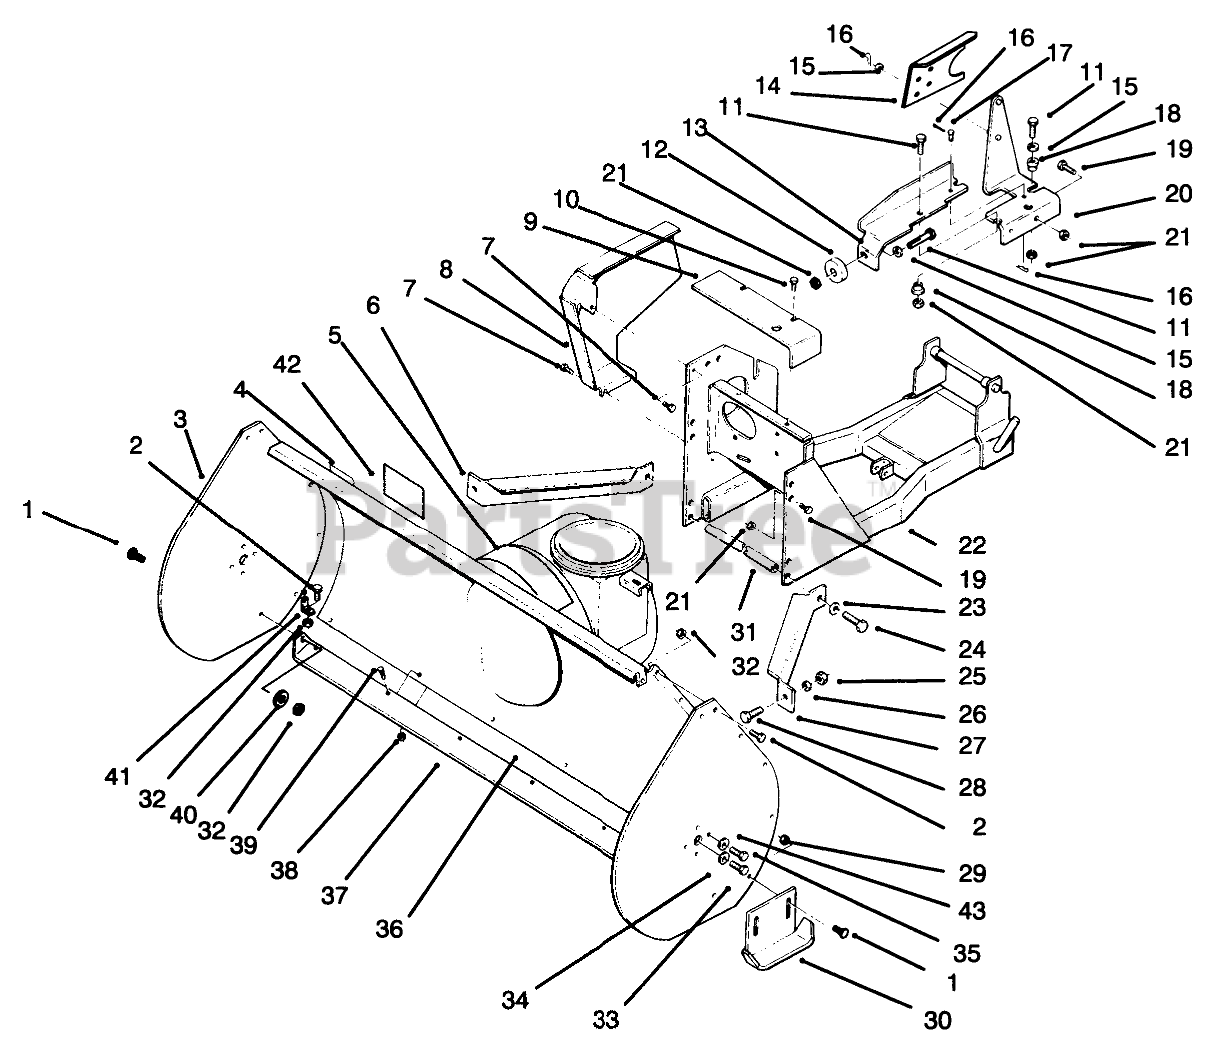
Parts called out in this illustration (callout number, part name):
1	BOLT-CARR
2	SCREW-HH
3	Plate-Side
4	DECAL-DANGER
5	DECAL-ATTACHMENT
6	BRACE-R.H. R
7	SCREW-HWH
8	WLDMT-BELT COVER R
9	GUARD R
10	SCREW
11	SCREW-HH
13	BRACKET-BUMPER R
14	GUARD-BELT R
15	WASHER-FLAT
16	PIN-HAIR
17	Pin-Clevis
18	SPACER-LIFT LINK
19	SCREW-HH
20	WLDMT-BRKT GUARD R
21	NUT-LOCK, NI
22	WLDMT-CARRIER FRA R
23	WASHER-LOCK
24	SCREW-HH
25	NUT-LOCK, NI
26	WASHER-FLAT
27	BRACE-L.H. R
28	SCREW-CARR
30	Skid
31	BRACE-CROSS R
32	NUT-LOCK, NI
33	SCREW-HH, LOCK
34	WASHER
35	SCREW-HH
36	Housing-Auger (Incl. Ref. #4 & 42)
37	Blade-Scraper
38	NUT-LOCK, NI
39	SCREW-CARR
40	WASHER-PLAIN
41	BLADE SUPPORT BRKT R
42	DECAL-WARNING
43	WASHER-FLAT
